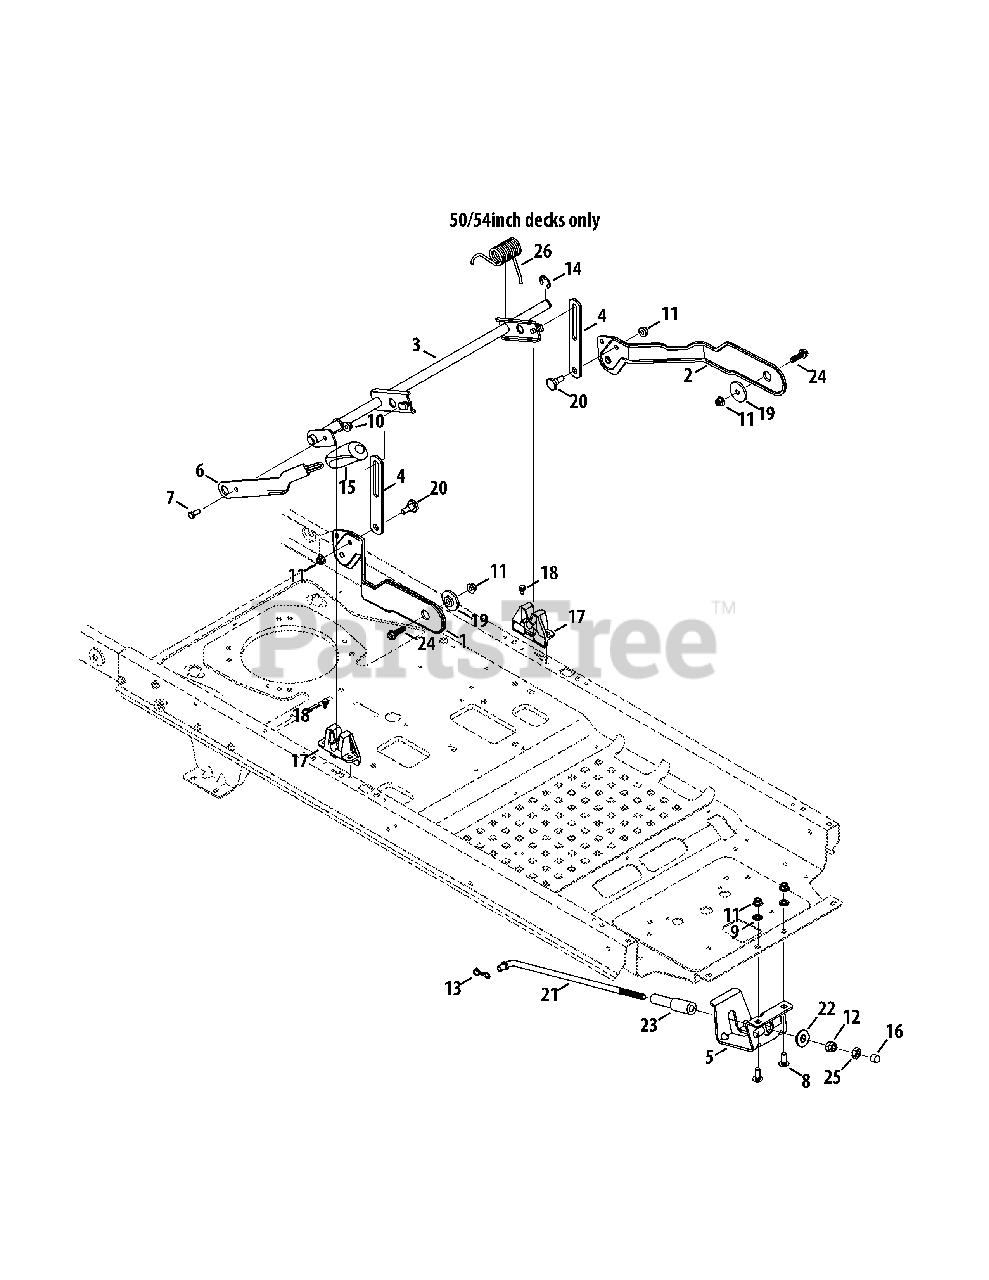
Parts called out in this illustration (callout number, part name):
1	Deck Lift Plate, RH
2	Deck Lift Plate, LH
3	Deck Lift Shift Assembly
4	Lift Link Plate
5	Rod Support Mounting Bracket
6	Deck Lift Handle
7	SCREW 5/16-18 x .75 GR5
8	Carriage Bolt, 3/8-16 x 1.00
9	Push Nut, 3/8
10	Flange Lock Nut, 5/16-18
11	Flange Lock Nut, 3/8-16
12	Hex Nut, 1/2-13
13	Bow-Tie Cotter Pin
14	E-Type Ring, .750
15	Grip, .50 ID
16	End Cap
17	DECK LIFT BRACKET
18	Shoulder Screw, .500 x 1/4-20
19	SHOULDER SPACER -S
20	Shoulder Screw, .500 Dia. x .434
21	Deck Lift Rod
22	Deck Lift pivot Cup
23	Nylon Sleeve, .55 ID x 4.50 LG
24	Screw, 3/8-16 x 1.00
25	Jam Nut, 1/2-13
26	Torsion Spring, 1.323 ID x 2.83 LG
